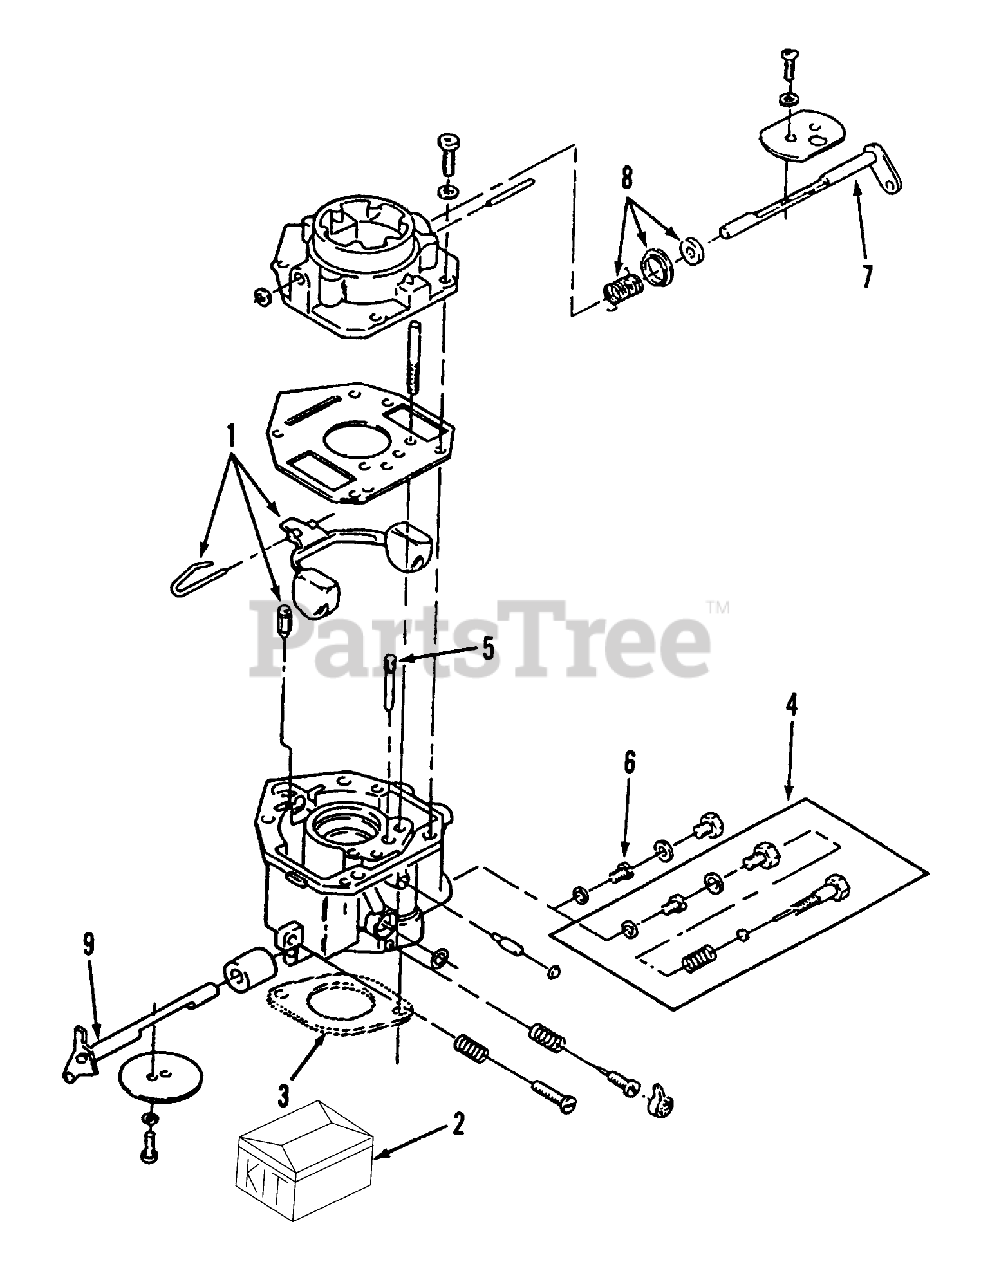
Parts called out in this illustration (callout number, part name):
2	REPAIR KIT
4	FIXED-JET
5	IDLE-JET
